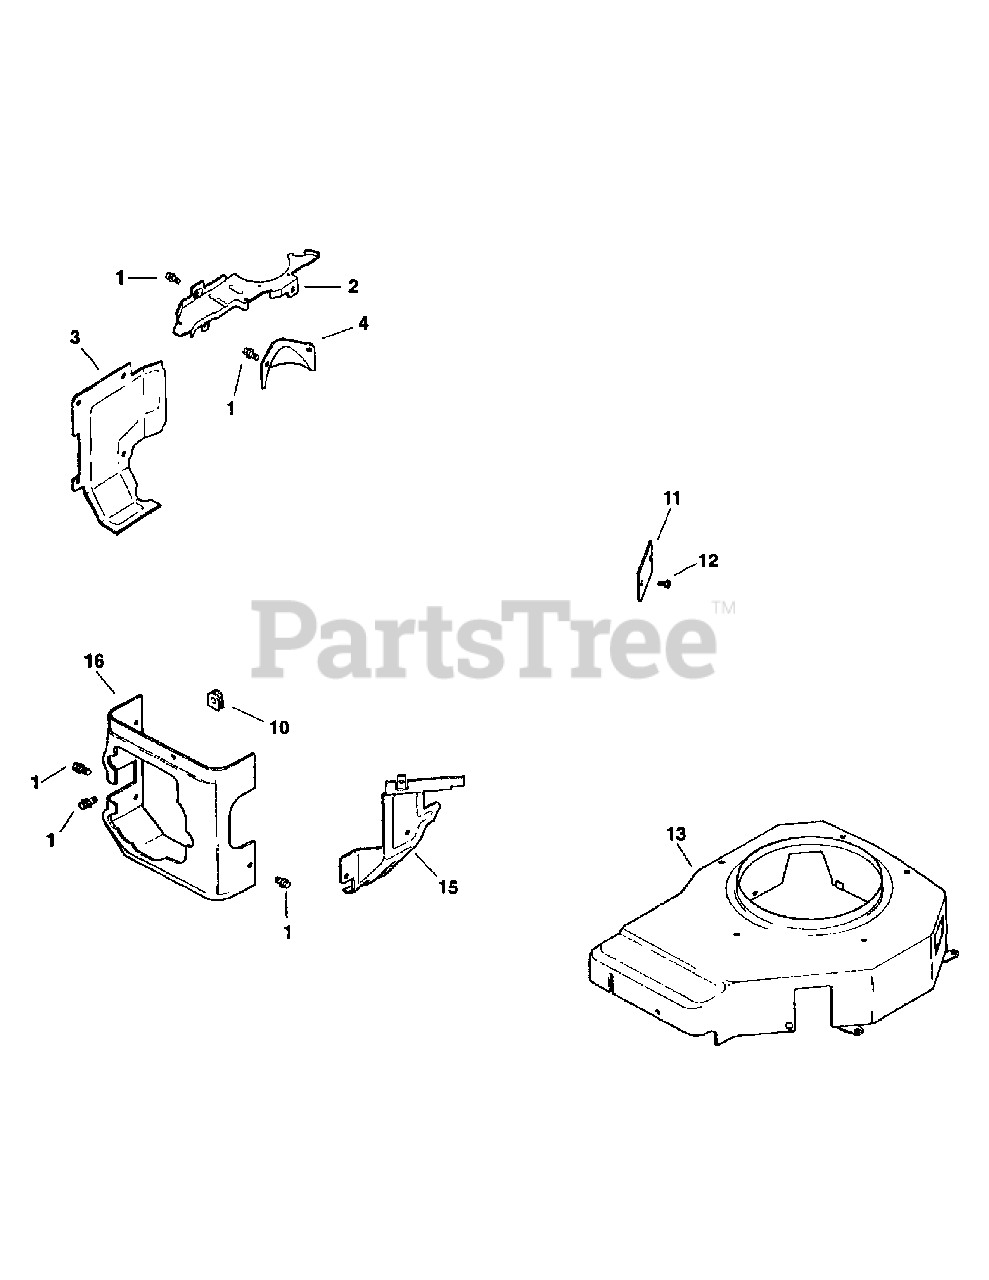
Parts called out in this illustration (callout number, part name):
1	Screw, Hex Flange
2	Plate, Blower Housing Back
3	Baffle, Cylinder Barrel
4	Cover, Starter
10	Grommet, Blower Housing
11	Cover, Regulator
12	Screw, Hex Flange
13	Housing, Blower
15	Baffle, Intake Side
16	Baffle, Cylinder Head
